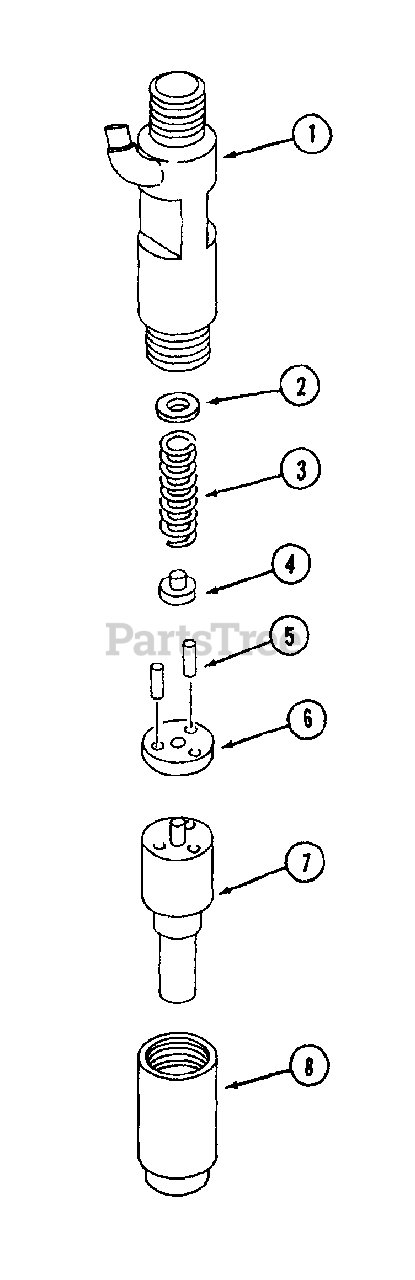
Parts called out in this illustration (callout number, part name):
1	Body Sub Ass'y.
2	Washer
3	Spring, Pressure
4	Pin, Pressure
5	Pin, Straight
7	Nozzle Ass'y.
8	Nut, Nozzle Retaining
